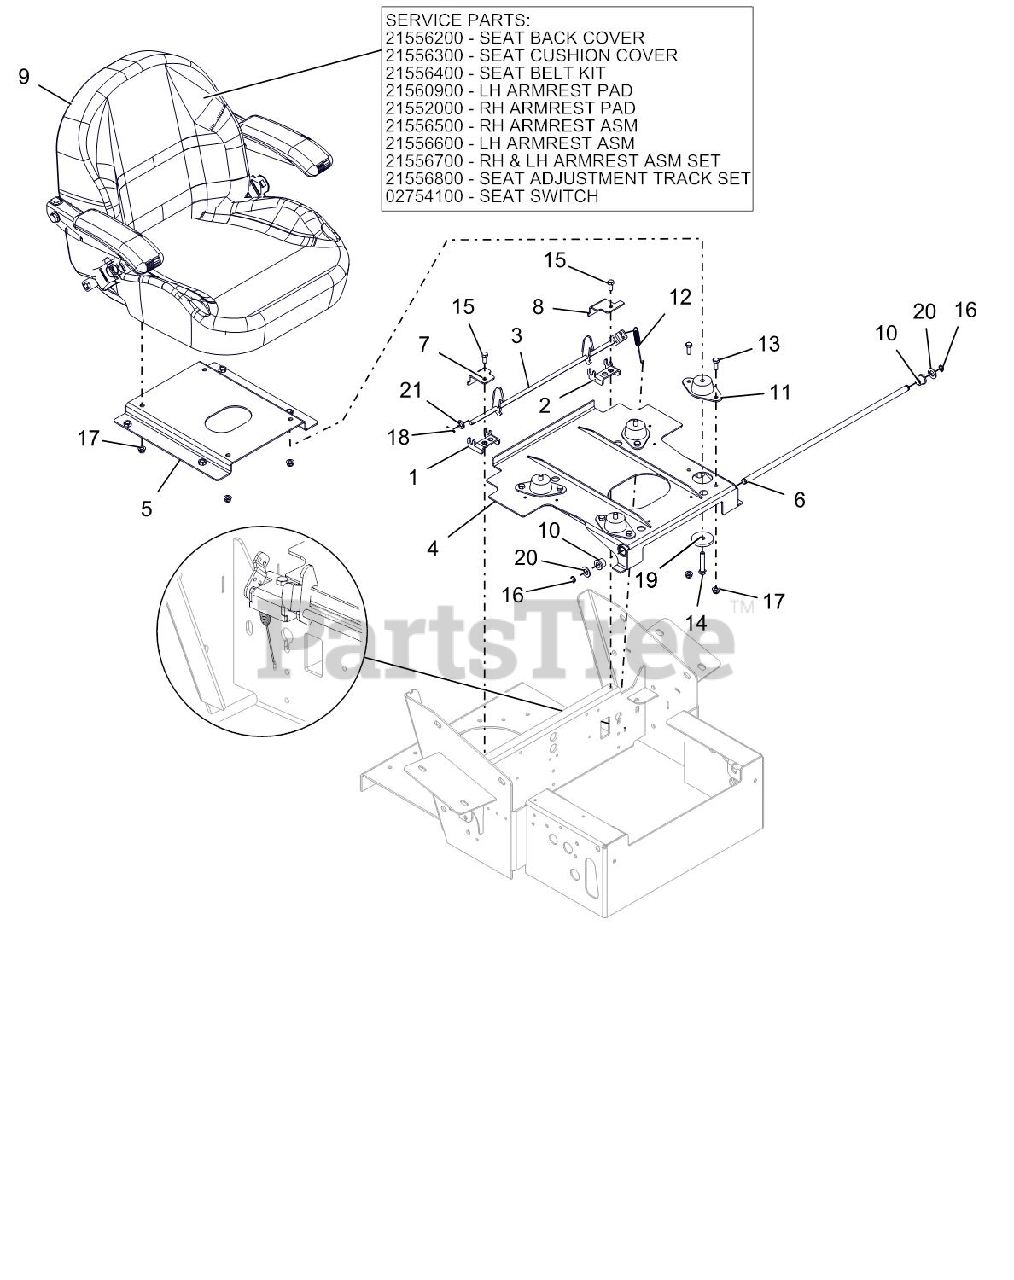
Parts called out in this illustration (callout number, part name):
1	PT100 RH SEAT LATCH MNT WMT-BL
2	PT100 LH SEAT LATCH MNT WMT-BL
3	PT100 SEAT LATCH WLDMT - BLACK
4	PT ISOLATOR MTG PLATE WMT -BLK
5	SEAT PLATE WLDMT - BLACK
6	SHAFT, PT100 SEAT PIVOT
7	PT100 RH TOP SEAT LATCH MNT-BL
8	PT100 LH TOP SEAT LATCH MNT-BL
9	SWITCH- SNAP MTG N.O.
9	PAD, ARMREST
9	COVER, SEAT BACK
9	COVER, SEAT CUSHION
9	KIT, SEAT BELT
9	ARMREST, RH ASSEMBLY
9	ARMREST, LH ASSEMBLY
9	SET, RH & LH ARMREST ASSEMBLY
9	SET, SEAT ADJUSTMENT TRACK
9	PAD, ARMREST (HARD)
9	SEAT, NON-SUSPENSION
10	BSHG, FLG .516X.750X.625X.937
11	MOUNT, FAIL-SAFE COMPRESSION
12	SG-TENS .043X.44X3.31 WLD 5.8
13	BOLT-HEX.31-18X.875 YWZC GR5
14	@BLT-HEX .38-16X2.00 GR5 YWZC
15	@BLT-HEX .31-18X.75 GR5 YWZC
16	RG-RTNG-EXT .500X.050 (SNAP)
17	@NUT-LK-NYL-FLG .31-18 YWZC
18	@PIN-CTR .09X.75 EXTPRSQCT YWZ
19	WSHR-FL-STL .469X2.00X.25 YWZC
20	WSHR-FL-STL.531X1.00X.063 YWZC
21	@WSHR-FL-STL.406X.812X.065 YWZ
